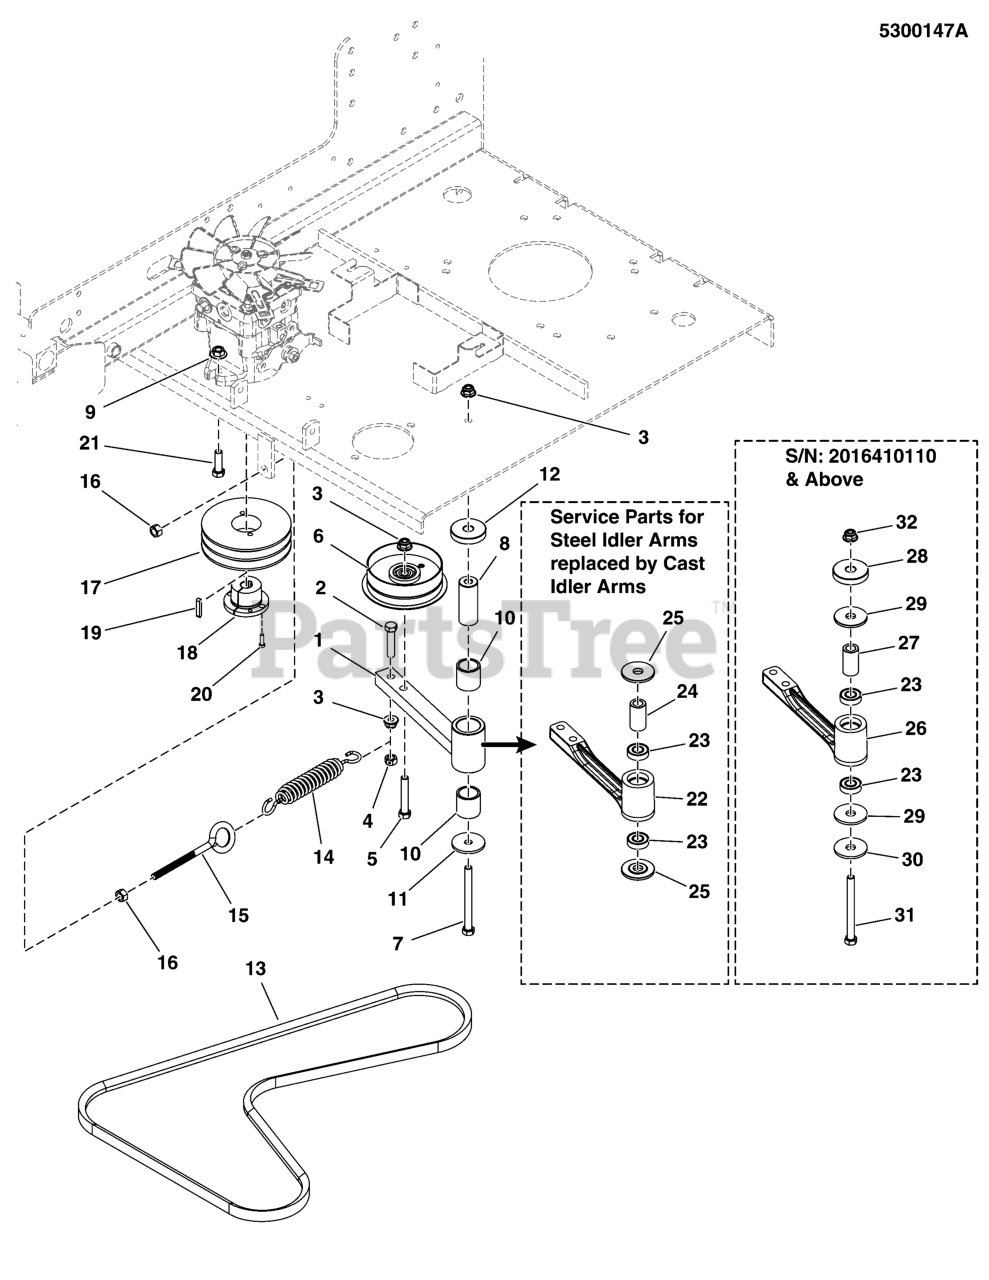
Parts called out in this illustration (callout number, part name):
2	BOLT, 3/8-16 X 1-3/4" GD5 CZ
3	NUT, 3/8-16 HEX NYLOCK FLANGE
4	NUT, 3/8-16 HEX SIDE LOCK
5	BOLT, 3/8-16 X 2-1/4" GD5 CZ
6	PULLEY, SINGLE FLANGED, 4"ODX3/8"ID
7	BOLT, 3/8-16 X 4" GD5 CZ
8	SPACER, .39 X 1.00 X 2.55, SS
9	NUT, 3/8-16 HEX SERRATED FLANGE
10	BUSHING, BRASS, 1.25X1X1.25
11	WASHER, .41 X 1.75 X .14
12	SPACER, .45 X 1.88 X .38
13	BELT, BANDED A-SEC,64.76EL,POLY,RAW EDGE
14	SPRING-EXT, 1.04 ODX6.935LGX.148WR, BLK
15	EYE BOLT, 3/8-16 X 6, 3THRD, 1EYE, CZ
16	NUT, 3/8-16 HEX
17	PULLEY, PUMP DRIVE
18	BUSHING, TAPERED HUB
19	KEY, 5MM SQ. W/ RADIUS
20	BOLT, 1/4-20 X 1" GD5 CZ
21	BOLT, 3/8-16 X 1-1/4" GD5 CZ
22	ASSM, IDLER ARM, PUMP DRIVE, 3/8ID, CAST
23	BEARING, BALL, AXLE
24	SPACER, .39 X .88 X 1.53, CZ
25	SPACER, IDLER ARM, T-STYLE, CZ
26	ASSM, IDLER ARM, PUMP DRIVE, 1/2ID, CAST
27	SPACER, .52 X .84 X 1.53, PM
28	SPACER, .52 X 1.88 X .38
29	SPACER, IDLER ARM, 1/2, PM
30	WASHER, .52 X 1.75 X .14, CZ
31	BOLT, 1/2-13 X 4" GD5 CZ
32	NUT, Hex Flange, Nylock, 1/2-13
